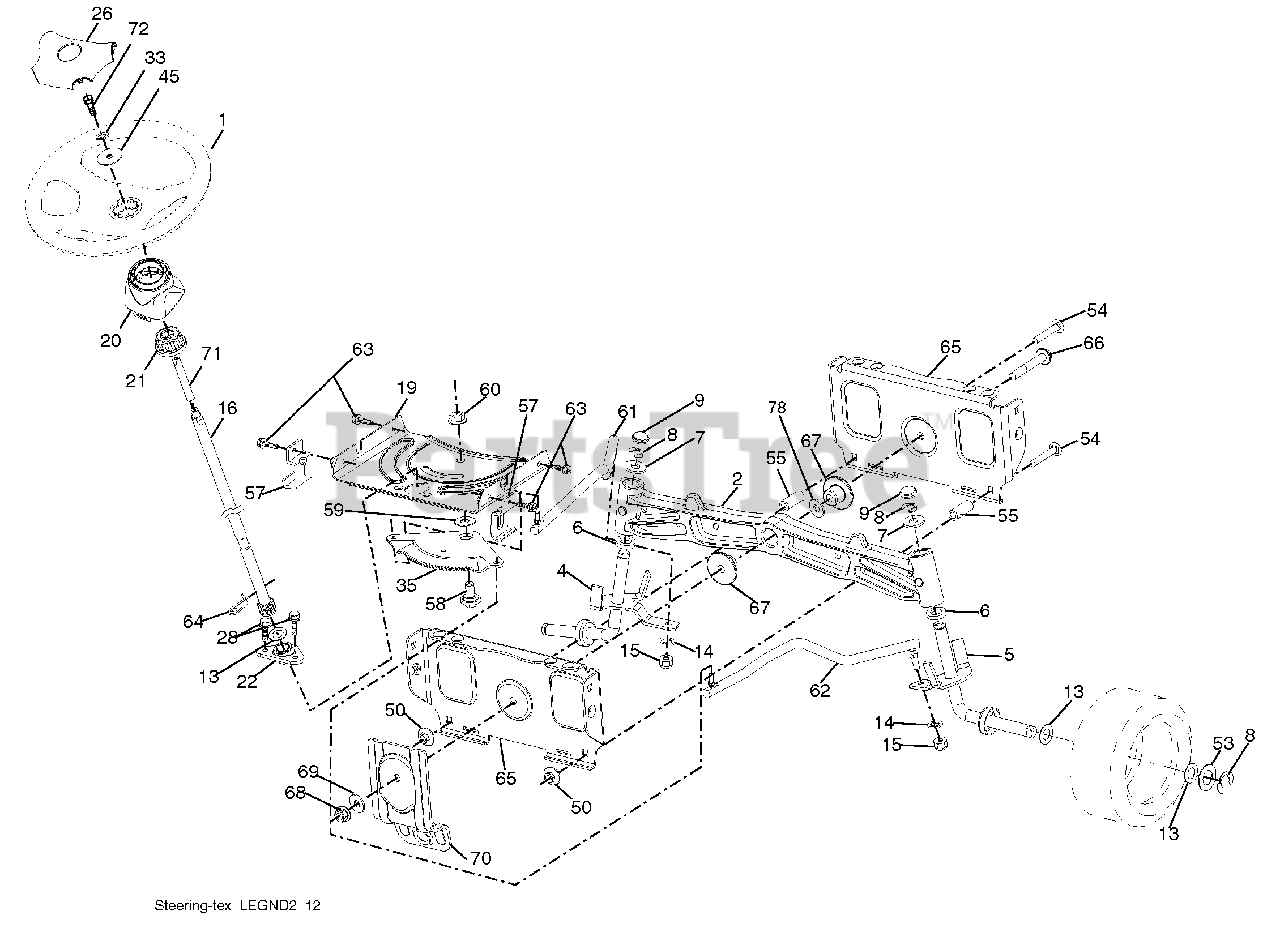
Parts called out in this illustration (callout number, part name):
1	Wheel, Steering
2	Axle Asm., Front
4	Spindle Asm., LH
5	Spindle Asm., RH
6	Bearing, Race Thrust Harden
7	Washer 25/32 x 1-5/8 x 16 Ga.
8	Ring, Clip #T5304-75
9	Cap, Spindle
13	Washer 25/32 x 1-1/4 x 16 Ga.
14	Washer Lock 3/8
15	Nut, Crown Lock 3/8-24 unf
16	Shaft Steering
19	Plate Steering
20	Boot, Steering
21	Adapter, Wheel Steering
22	Bushing, Strg. Blk
26	Insert, Wheel Steering
28	Screw 3/8-16 x 3/4
33	Washer Lock 5/16
35	Gear, Sector Plate
45	Washer 11/32 x 2-3/8 x 12 Ga.
50	Nut Lock Flg 3/8-16 unc
53	Washer Hardened .793 x 1.637 x .060
54	Bolt Hex HS 3/8-16 unc x 2-1/4
55	Spacer Brace Axle
57	Bracket Upstop
58	Bolt Shoulder Sector Pivot CFM
59	Washer Thrust Sector Steering
60	Nut Flange Lock 5/8-11
61	Draglink, LH
62	Draglink, RH
63	Screw 5/16-18 x 3/4
64	Retainer Clip Spring Steering
65	Brace Axle Front
66	Bolt Hex Fghd 7/16-14 x 3 Serr
67	Bushing PM Front Axle
68	Nut Lock Flange 7/16-14 Gr. 5
69	Washer 1.5 x .505 x .118
70	Bracket Deck Susp. Front
71	Shaft Ext. Steering
72	Bolt 5/16-18 x 4.5 Gr. 5
78	Washer Thrust .515 x .750 x .033
